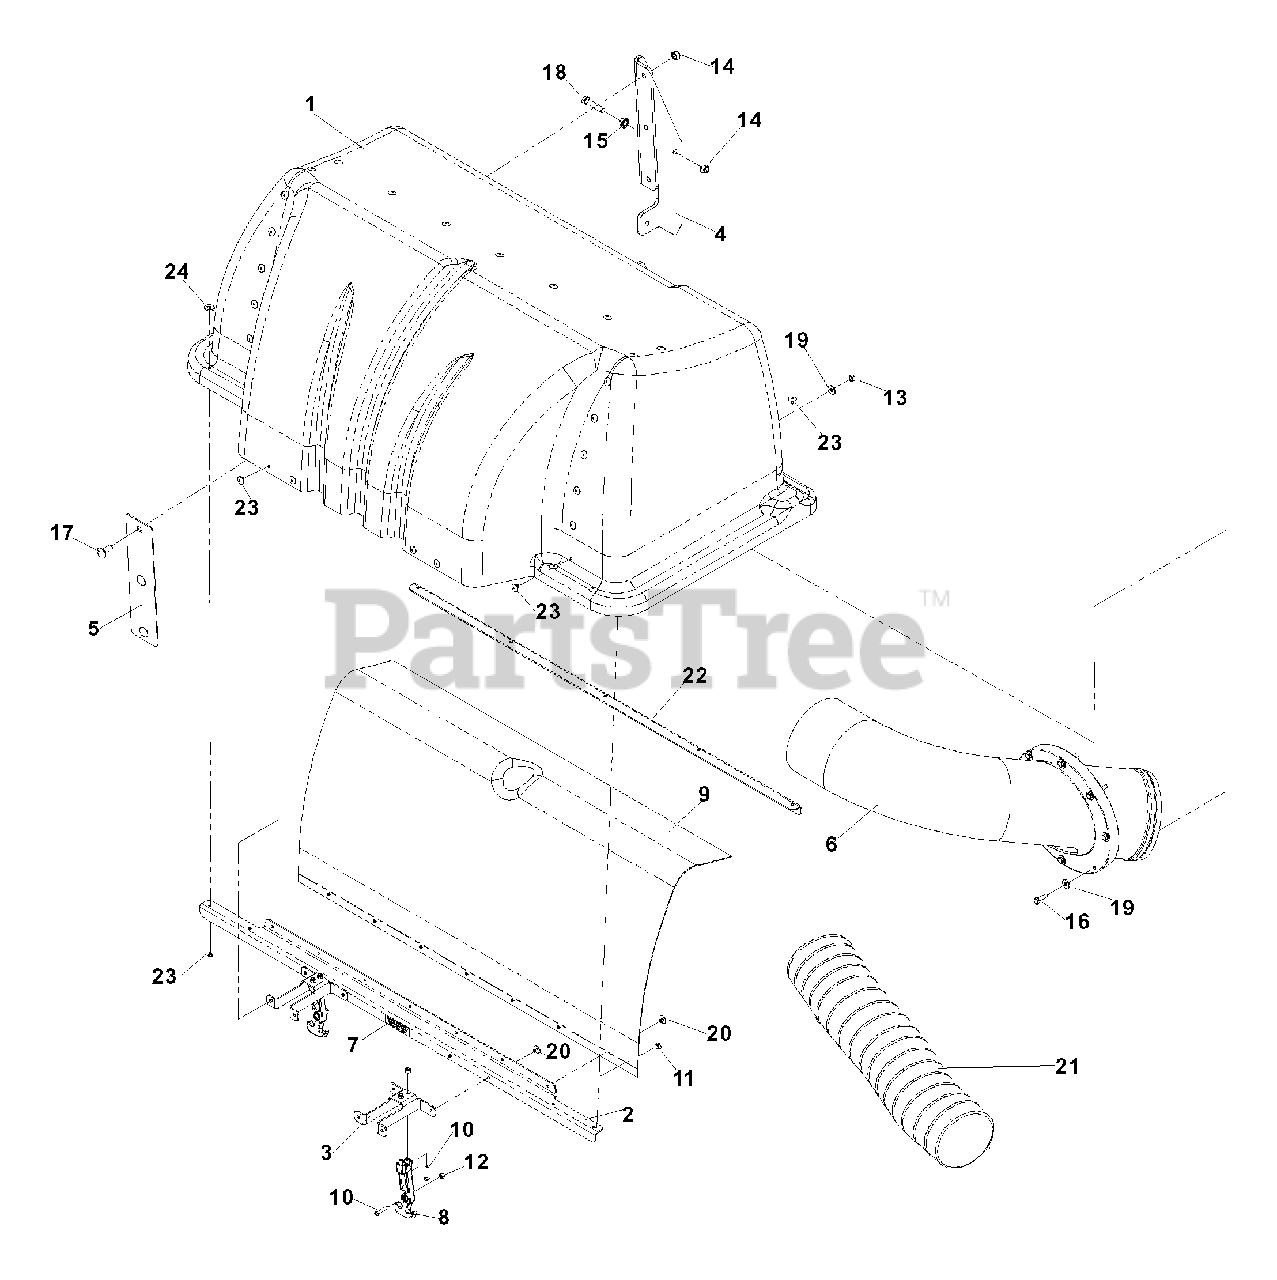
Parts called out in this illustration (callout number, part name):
2	HOOD SUPPORT
3	SUPPORT, DRAW LATCH
4	HOOD HINGE
5	MOUNT PLATE
6	INLET TUBE
7	DECAL, VENTILATION
8	DRAW LATCH, FLEX T-HNDLE
9	MESH, POLY DIAMOND
10	SCREW, #10-24 x 1 1/8 , MACH.
11	WASHER, #10
12	NUT, #10-24, NYLOC
13	NUT, 1/4C, NYLOC
14	NUT, 3/8 C, NYLOC
16	HCS, 1/4 -20 x 1 3/4
17	RHSNB, 3/8 -16 x 1
18	HCS, 3/8 -16 x 1 3/4
19	WASHER, 1/4
20	RIVET, 3/16 x 1/4
21	HOSE, 58", MODEL HCS13
21	HOSE, MODEL HCS1372
22	HOOD SUPPORT, REAR
23	RIVET, 1/4 STAVEX
24	WASHER, #10
